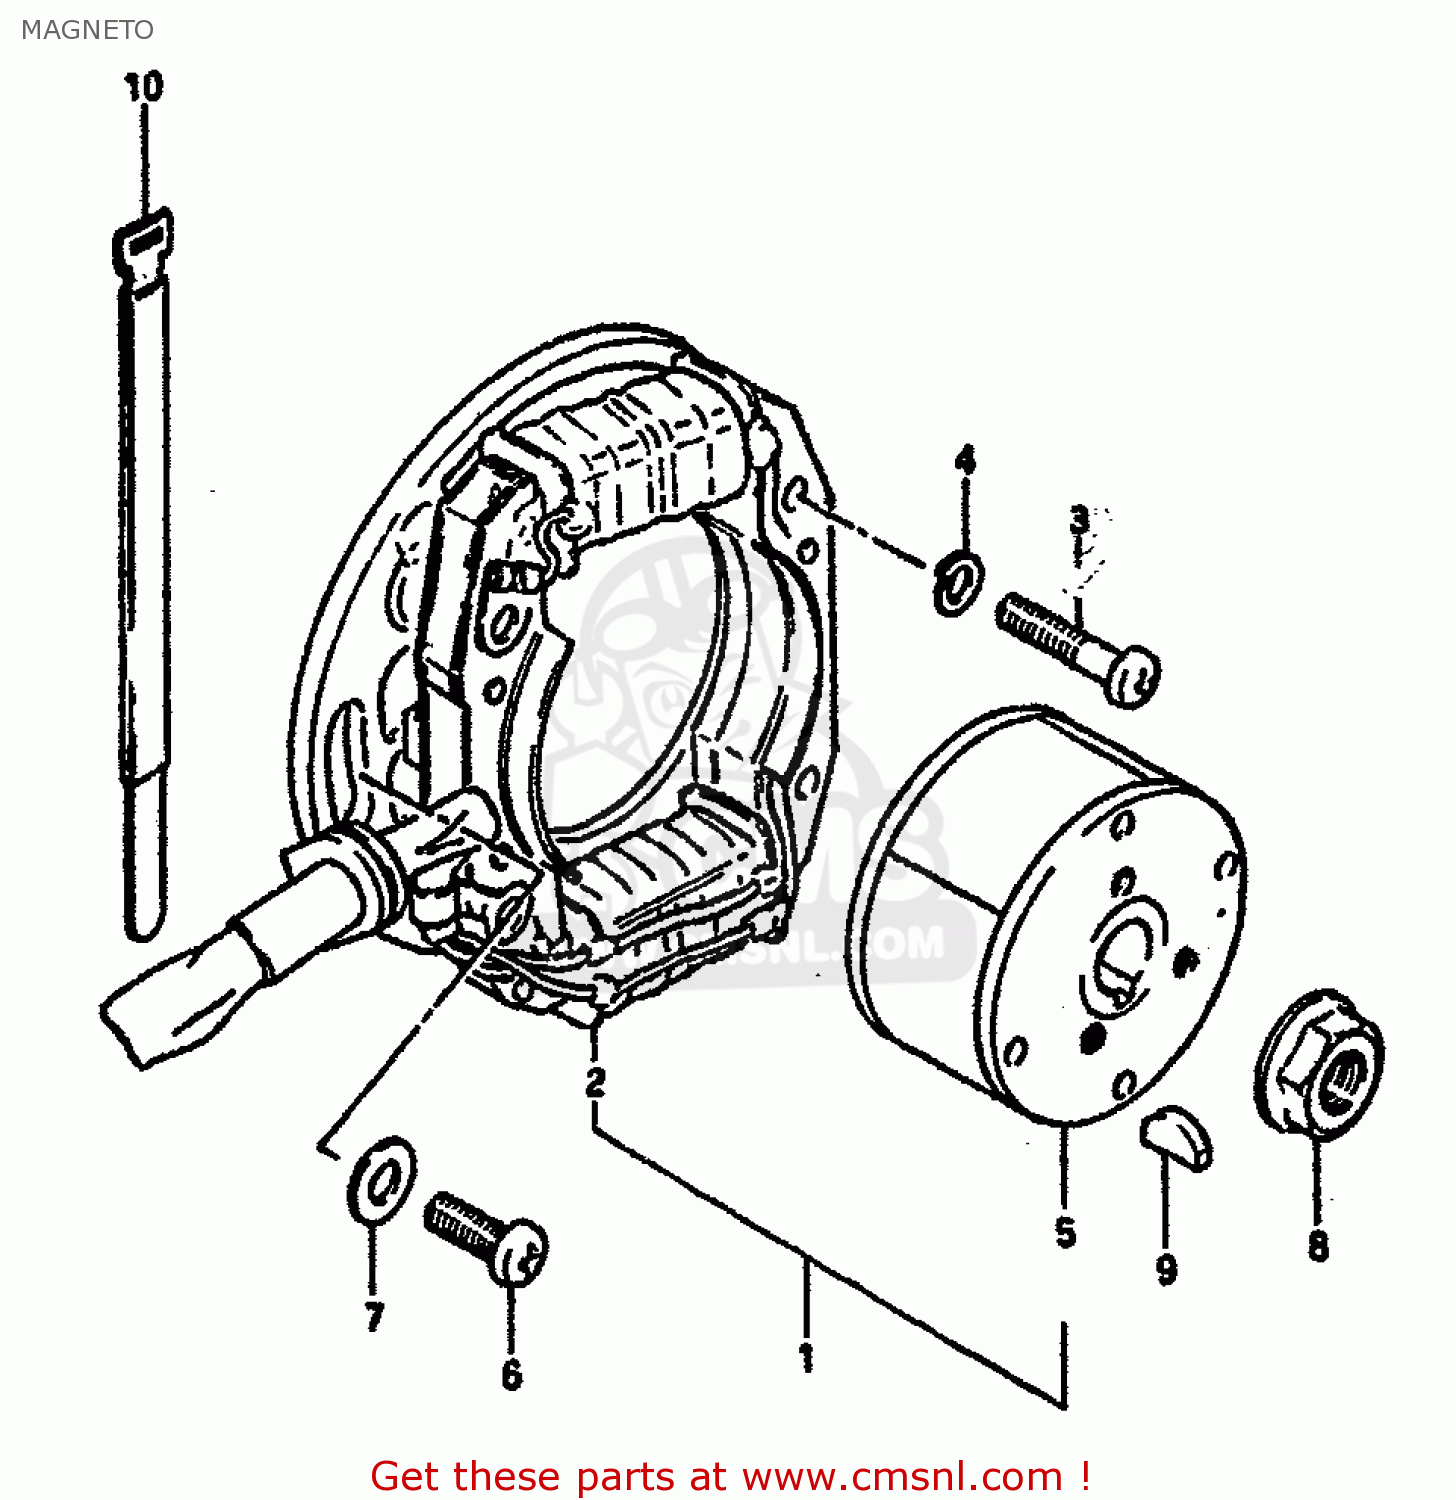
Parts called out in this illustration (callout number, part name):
1	MAGNETO ASSEMBLY
2	STATOR ASSEMBLY
3	SCREW 5X20
4	LOCK WASHER
5	ROTOR ASSEMBLY
6	SCREW
7	WASHER
8	NUT
9	KEY 4MM
10	CLAMP
